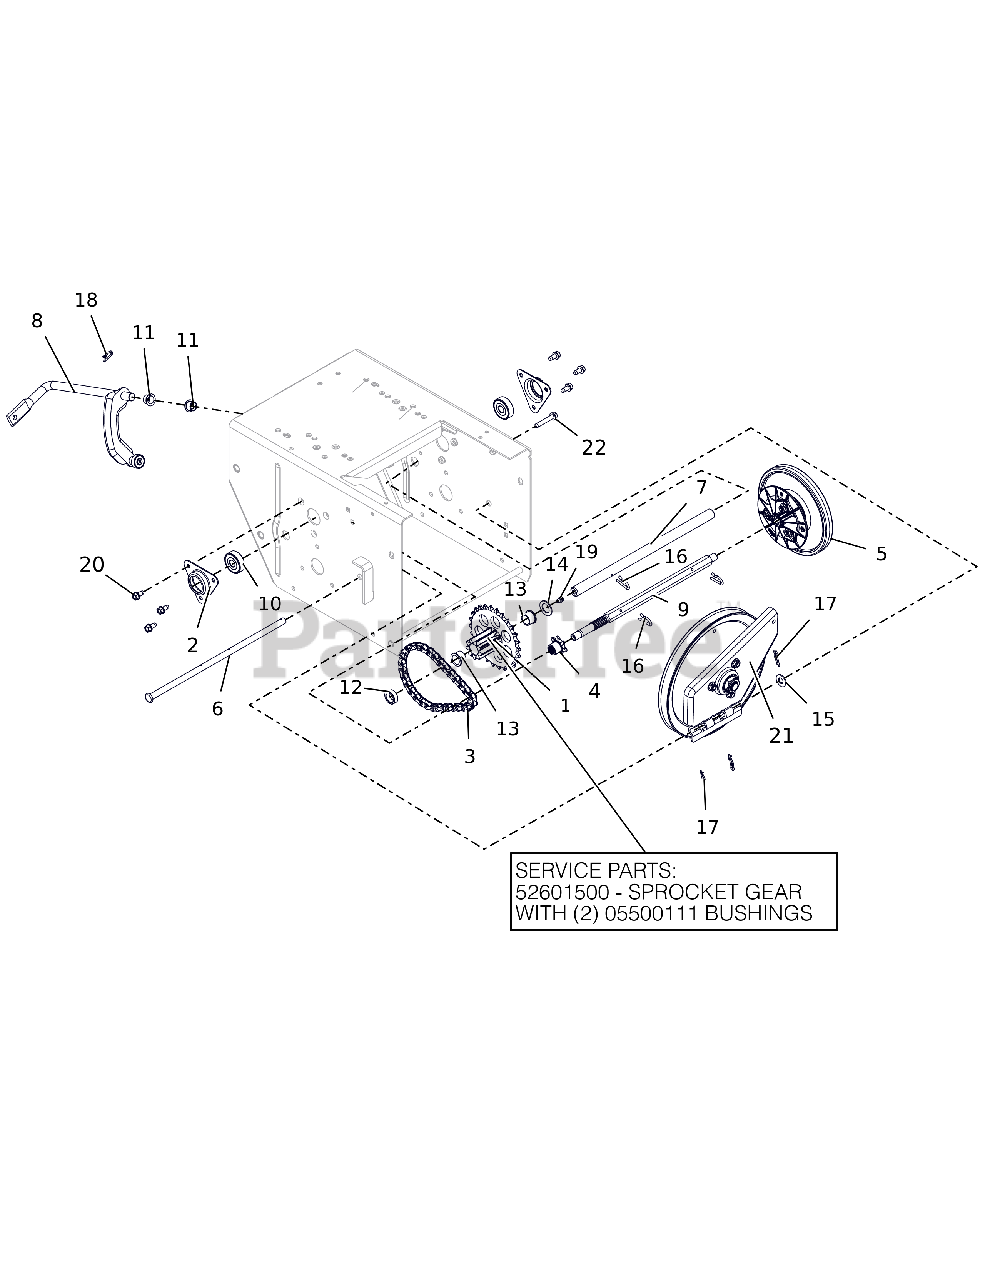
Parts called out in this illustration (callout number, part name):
1	PINION & SPROCKET
1	PINION & SPROCKET W/BUSHINGS
1	BSHG-FLG .625X.750X.500X.875
2	FLANGE, BEARING
3	CHAIN - #41, 32 PITCHES
4	SPROCKET, PINION 7T W/SPLINE
5	DISC, FRICTION DRIVE-ASSEMBLY
6	PIN, PIVOT
7	SHAFT, PINION-HARDENED
8	ARM, SHIFT - ASSEMBLY
9	SHAFT, HEX - HEAT TREATED
10	BRG-BALL .437X1.375X.437
11	BUSHING, POLYLINER-.50 SPLIT
12	BSHG-SLV, .635X.880X.305
13	BSHG-FLG .625X.750X.500X.875
14	WSHR-FL-STL .630X1.005X.062 YZ
15	@WSHR-FL-STL.406X.812X.065 YWZ
16	PIN, SPRING CLIP
17	PIN-HAIR, ENDRIES #25 YWZC
18	CLIP, SPRING
19	ZERK,FITTING .25X.125 DRIVE IN
20	SCR-TAP .25-20X.50 HWH TR YWZ
21	PLATE, SWING ASSEMBLY-DEEP
22	@SCR-TAP .25-20X1.50 HWH TR YZ
